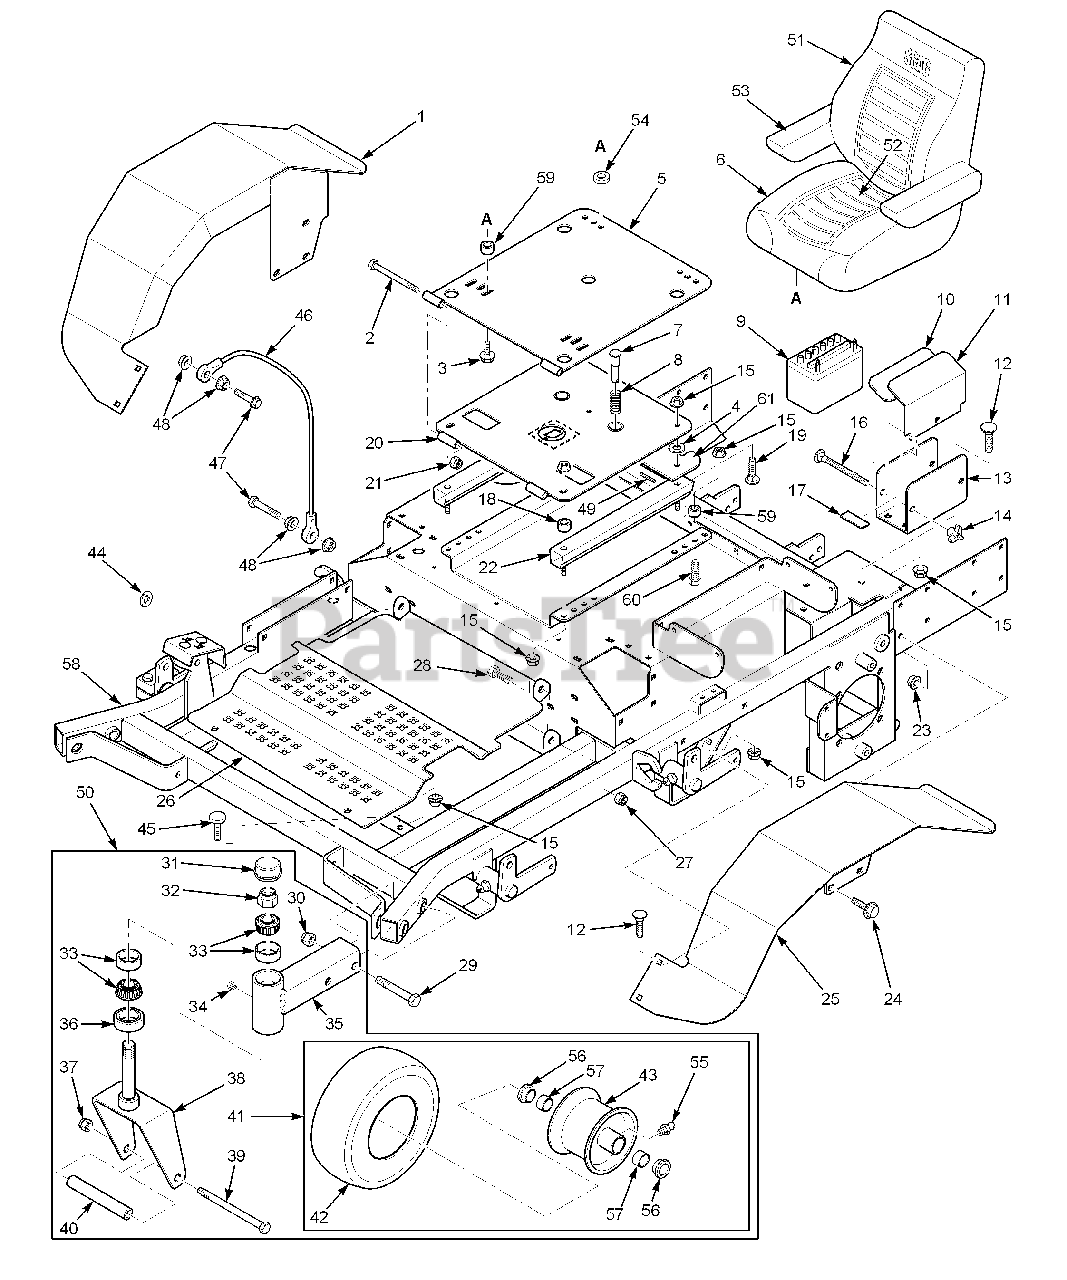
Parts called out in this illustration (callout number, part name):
1	Fender Weldment, RH
2	Bolt, Hex Head 5/16-18 x 3-1/2"
3	Screw, Hex Serrated Flange 5/16-18 x 3/4"
4	Flatwasher, 3/8"
5	Seat Plate Weldment, Upper
6	Seat Assembly w/armrest
7	Pin Retainer, Spring
8	Spring, Seat
9	Battery
10	Pad, Battery Cover
11	Cover, Battery
12	Bolt, Carriage 5/16-18 x 3/4"
13	Plate, Battery Box
14	Wing Nut, 1/4-20 x 3/4"
15	Nut, Hex Serrated Flange 5/16-18
16	Bolt, Carriage 1/4-20 x 6"
17	Rubber Pad
18	Spacer
19	Bolt, Carriage 5/16-18 x 1"
20	Seat Plate Weldment, Lower
21	Nut, Hex Elastic Stop 5/16-18
22	Seat Adjustment, Track Set
23	Nut, Hex Serrated Flange 3/8-16
24	Screw, Hex Serrated Flange 3/8-16 x 1"
25	Fender Weldment, LH
26	Foot Plate
27	Nut, Hex Elastic Stop 3/8-16
28	Bolt, Hex Head 3/8-16 x 1-1/4"
29	Bolt, Hex Head 5/8-11 x 4"
30	Nut, Hex Elastic Stop 5/8-11
31	Cap, Grease
32	Nut, Hex Elastic Stop 1.0-14
33	Bearing W/Race
34	Plug, 1/4-28 THD Form
35	Extention Weldment, Caster 72A
36	Seal, 2.00 OD. x 1.625 Bore
37	Nut, Hex Elastic Stop 1/2-13
38	Yoke Weldment, Caster
39	Bolt, Hex Head 1/2-13 x 7-1/2"
40	Sleeve
41	Wheel Assy
43	Rim Assembly
44	Washer, 3/8’
45	Bumper, Rubber
46	Cable, Seat Stop
47	Bolt, Hex Head 1/4-20 x 1-1/4"
48	Nut, Hex Serrated Flange 1/4-20
49	Roll Pin, Spring 5/32 x 3/4"
50	Caster Wheel Assy 72A
51	Back Cushion Cover
52	Seat Cushion Cover
53	Arm Rest, Both Sides
54	Spacer
55	Grease Fitting
56	Bearing, Oilite
57	Roller Bearing
58	Main Frame
59	Spacer, Seat
60	Bolt, Hex Head 5/16-18 x 1-3/4"
61	Stop, Seat
